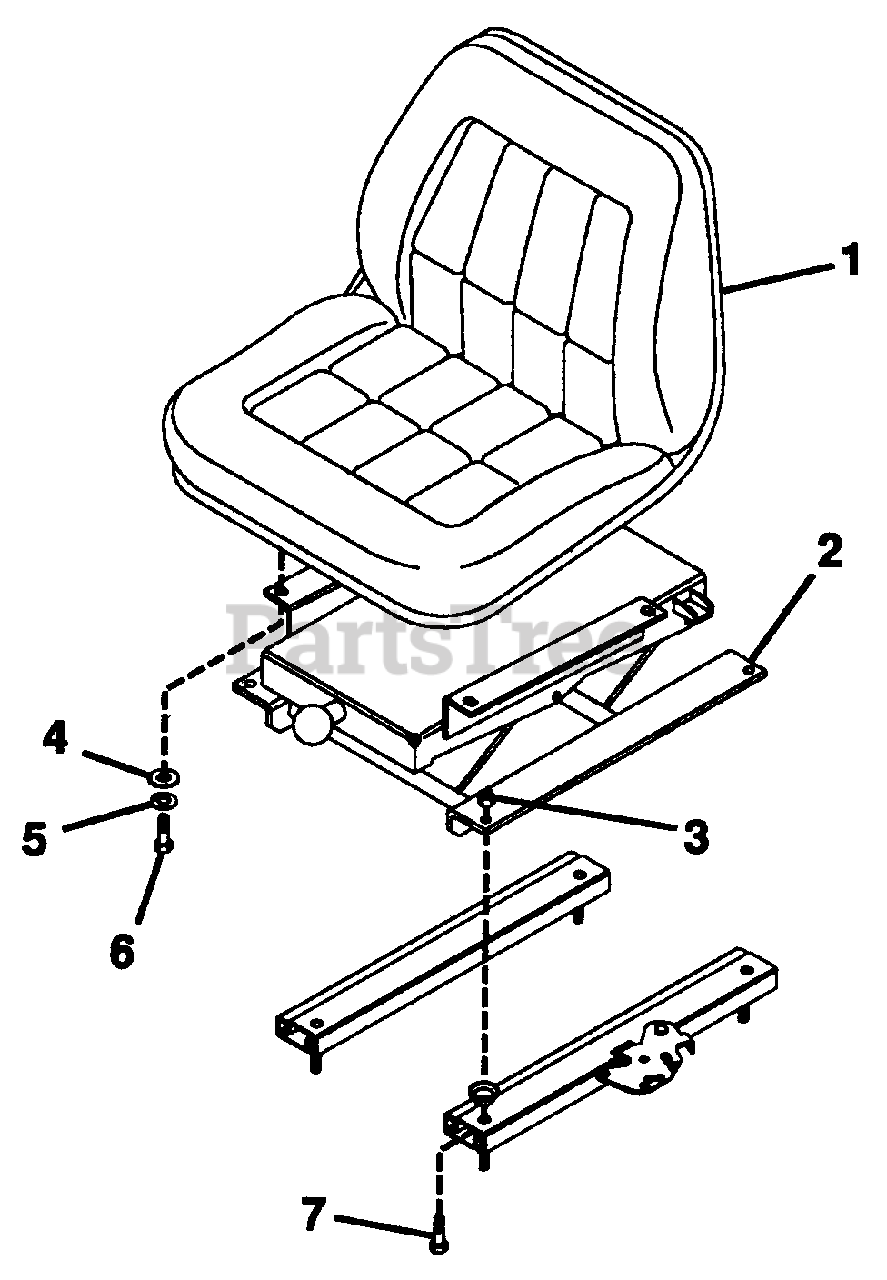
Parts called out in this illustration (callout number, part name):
1	Seat, ProMaster
2	Seat, Suspension
3	Nut, Lock 5/16-18
4	Washer, Flat .344x.688x.065
5	Washer, Lock 5/16 Reg.
6	Bolt, Hex 5/16-18x.75
7	Bolt, Hex 5/16-18x1.00
